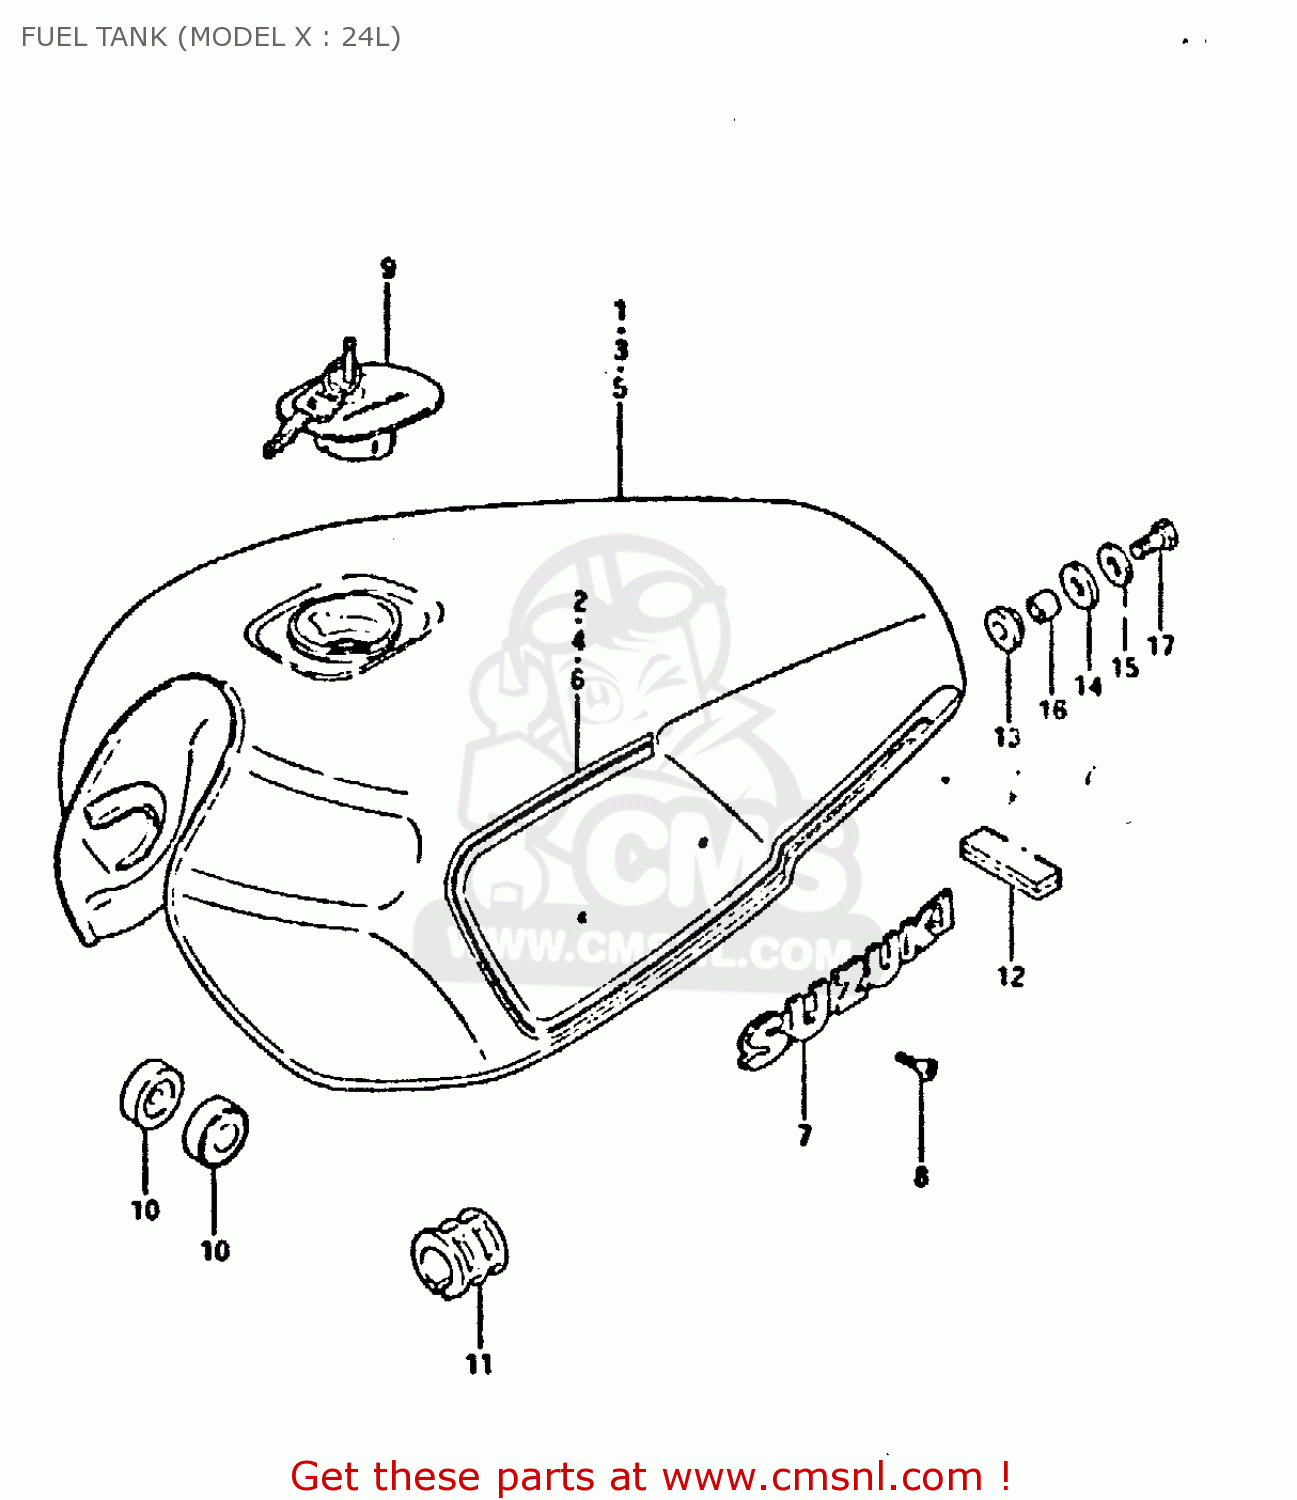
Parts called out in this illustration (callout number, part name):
1	TANK, FUEL (BLACK)
2	TAPE SET
3	TANK, FUEL (RED)
4	TAPE SET
5	TANK, FUEL (BLUE)
6	TAPE SET
7	EMBLEM,FUEL TANK
8	SCREW 3X6
9	CAP SET,FUEL TANK
10	CUSHION
11	CUSHION,FUEL TANK,UPPER
12	CUSHION
13	CUSHION
14	CUSHION
15	WASHER (8.5X29X1.6)
16	SPACER(8.5X12X19)
17	BOLT (8X30)
